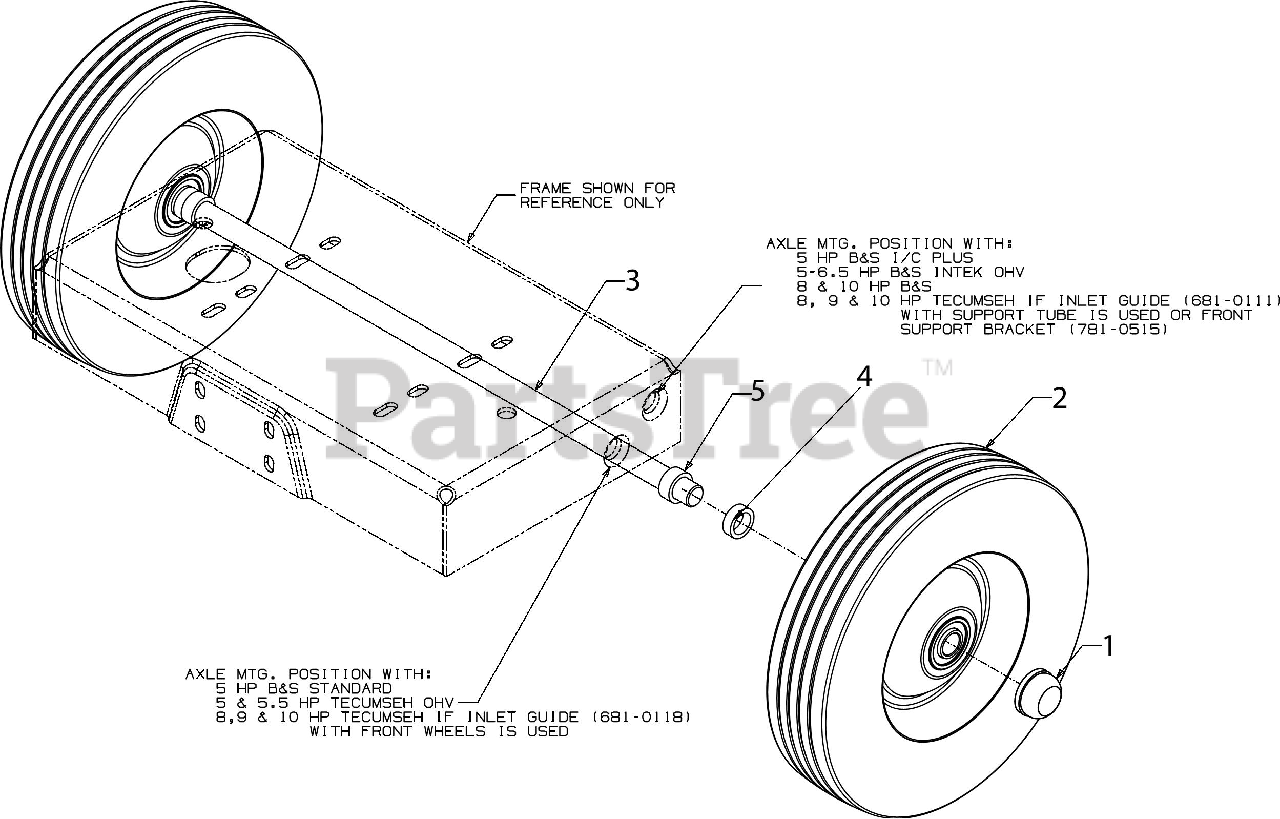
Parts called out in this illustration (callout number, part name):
1	PUSH CAP
2	WHEEL ASM-10" X 2.52 CS
3	SHREDDER AXLE
4	SPACER .632 x .877 x .281
5	SPACER
